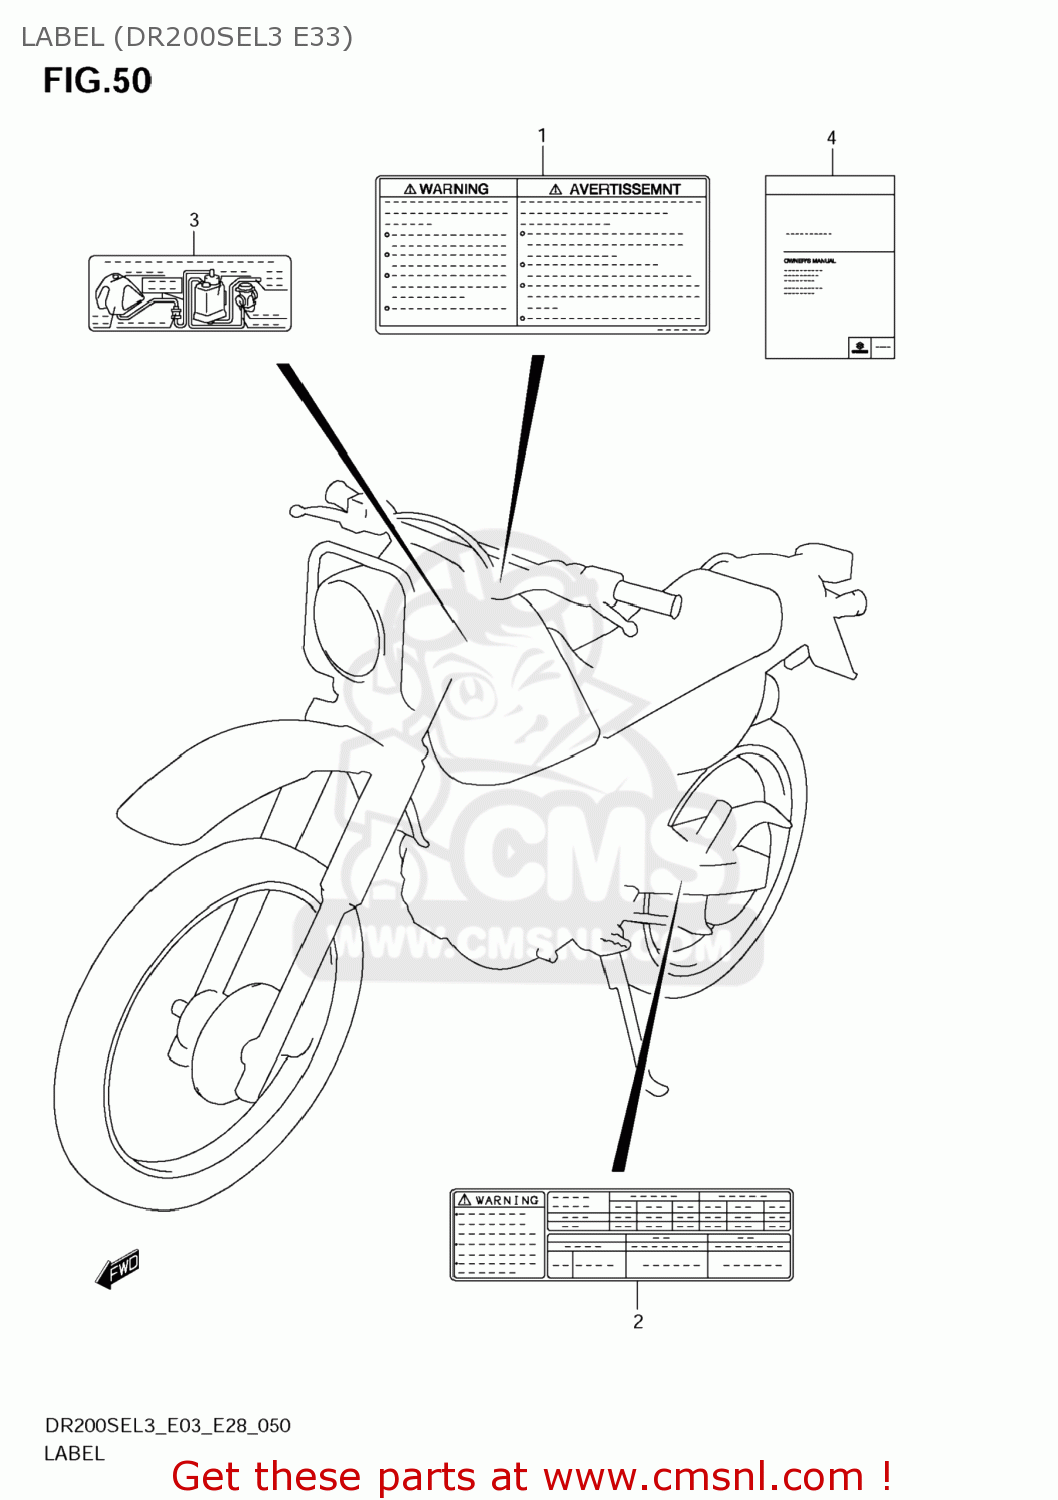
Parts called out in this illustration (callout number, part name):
1	LABEL,GENERAL WARNING
2	LABEL,TIRE INFORMATION
3	LABEL,PIPING DIAG
4	MANUAL,OWNER'S
